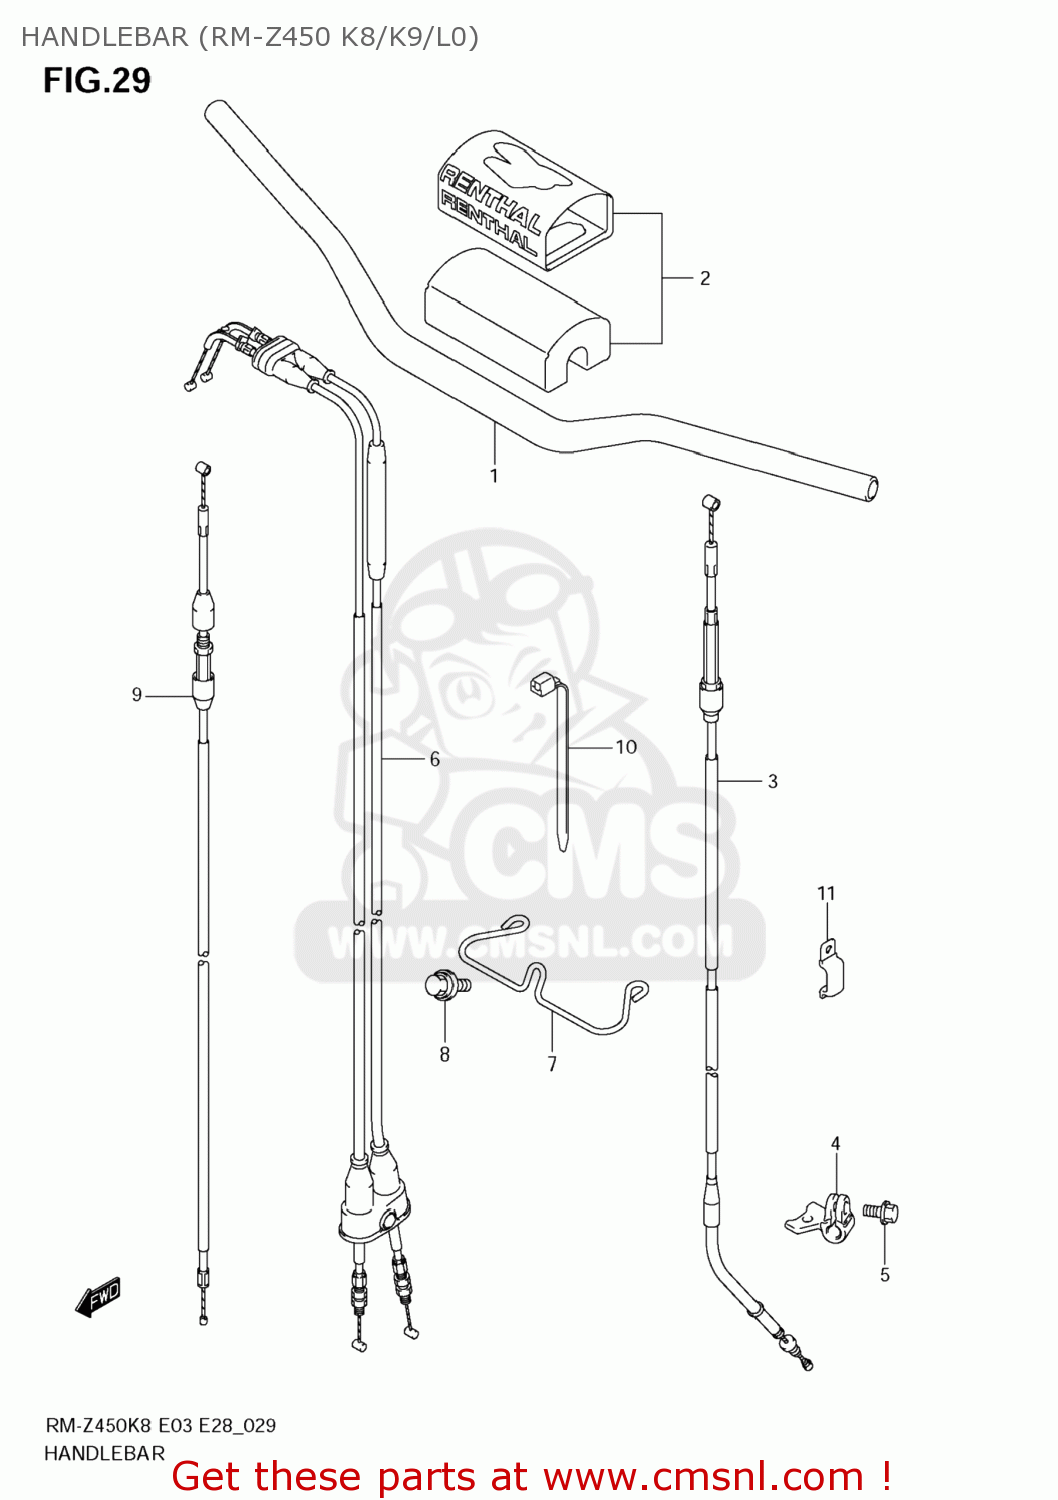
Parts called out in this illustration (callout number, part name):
1	HANDLEBAR
2	PAD SET,HANDLEBAR (NAS)
3	CABLE ASSY,CLUTCH
4	BRACKET,CLUTCH CABLE
5	BOLT(6X12)
6	CABLE SET,THROTTLE
7	GUIDE,CABLE
8	BOLT(6X16)
9	CABLE ASSY,HOT STARTER
10	CLAMP(L:95)
11	CLAMP
